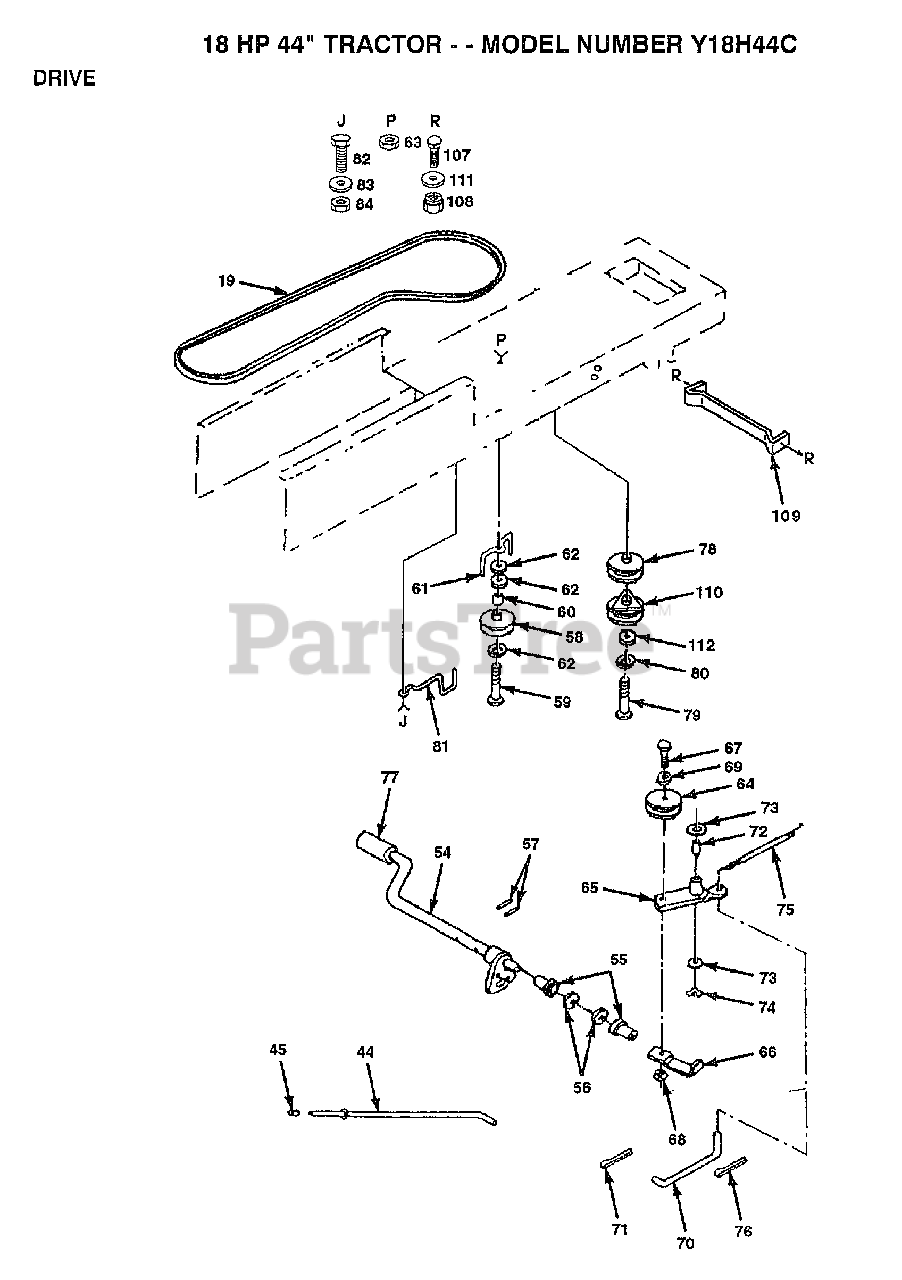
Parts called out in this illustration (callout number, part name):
44	BRAKE PARK ROD
45	PLUNGER CAP T
55	NYLON BEARING
56	WASHER LT
58	PULLEY.IDLER.FLAT
59	BOLT
60	SPACER T
61	BELT KEEPER LT
62	WASHER
65	ARM IDLER
66	RETAIN BELT
69	WASHER
70	"LINK, CLUTCH T"
71	COTTER PIN
72	"LY, BEARING"
73	WASHER LT
74	KLIP RING
75	"SPRING, RETURN LT"
76	COTTER PIN
77	PEDAL COVER T
78	PULLEY ENGINE
80	LOCKWASHER
81	KEEPER.BELT.ENG.L
82	BOLT
83	WASHER
107	BOLT
109	BRACKET.ASM.MTG
111	WASHER T
112	WASHER
